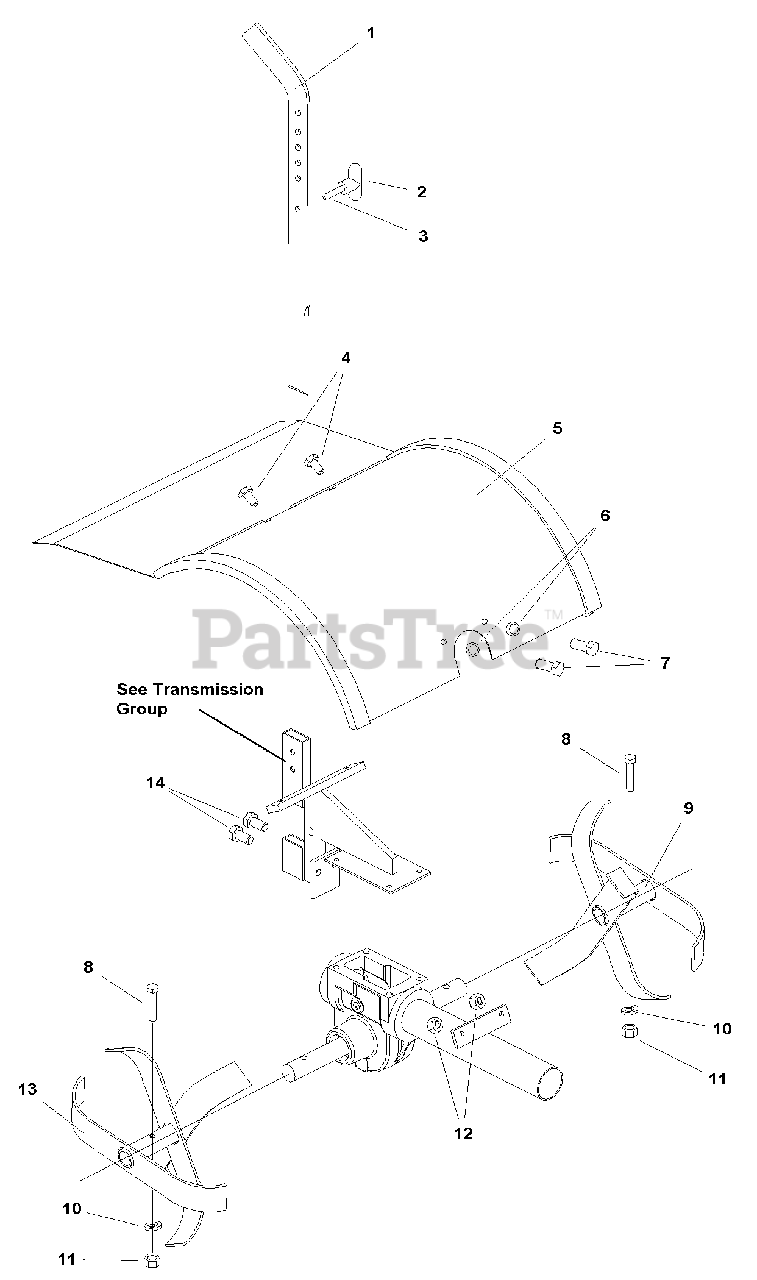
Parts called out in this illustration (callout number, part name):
1	LEVER, Depth Regulator RT
2	KNOB, T-Handle, Drag Stake
3	PIN, Detent 5/16" - 18 x 1"
4	CAPSCREW, Hex Head 1/4" - 20 x 1/2" G5
5	HOOD, Tiller, No Decal
6	LOCKWASHER, Spring 5/16"
7	CAPSCREW, Hex Head 5/16" - 18 x 1/2" G5
8	CAPSCREW, Hex Head 3/8" - 16 x 1-3/4" G5
9	TINE ASSEMBLY, LH
10	LOCKWASHER, Spring 3/8"
11	NUT, Hex 3/8" - 16NC, 2B
12	NUT, Hex Flange 5/16" - 18 Two, Way Lock GA
13	TINE ASSEMBLY, RH
14	BOLT, Hex Flange Head 5/16"-18 x 1/2"
